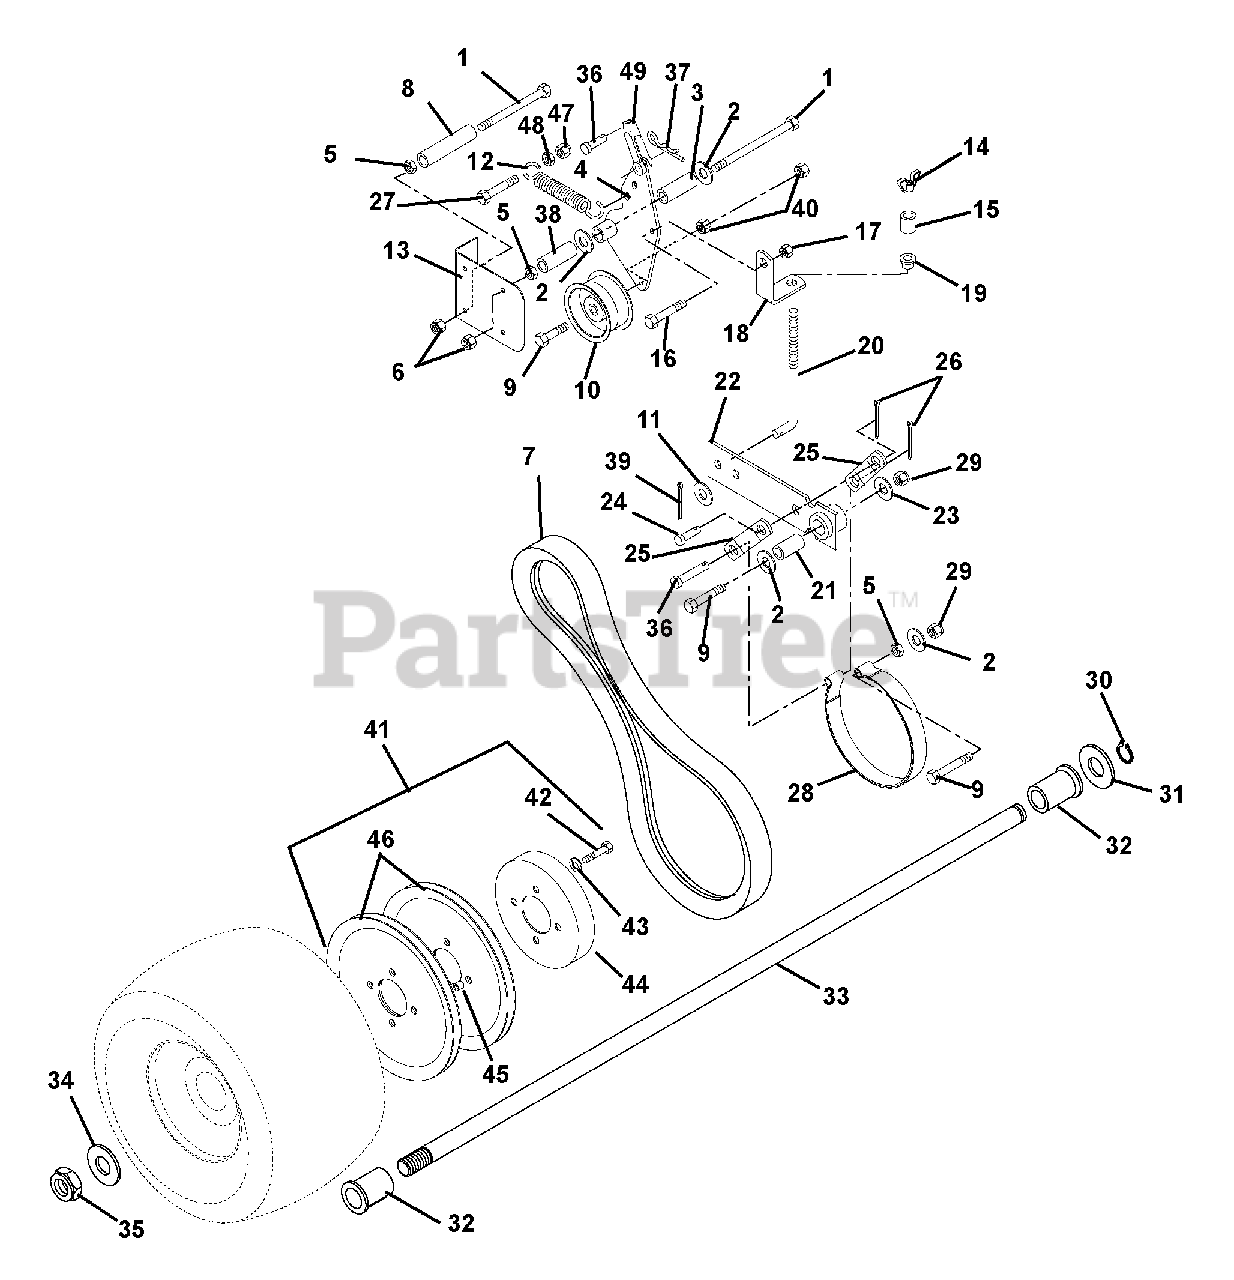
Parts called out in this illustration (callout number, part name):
1	@BLT-HEX .38-16X4.50 GR5 YWZC
2	@WSHR-FL-STL.406X.812X.065 YWZ
3	BUSH.,S.385X.610X1.80 ST
4	WMT - WHEEL CLUTCH ARM
5	@NUT-HEX .38-16 YWZC
6	@NUT-LK-TOP-FLG .38-16 YWZC
7	BELT, TRACTION DRIVE
7	BELT - TRACTION DRIVE - PRO
8	BSHG, SPACER, 3.25X3/8IDX5/8OD
9	@BLT-HEX .38-16X2.00 GR5 YWZC
10	IDLER 2.75X1.25
11	@WSHR-FL-STL.344X.688X.065YWZC
12	SG-TENS .105X1.00X5.0
13	KIT-BELT COVER W/DECALS
14	NUT-NYLK WING .312-18 YWZC
15	BSHG-SLV .391X.688X.52 PM
16	@BLT-HEX .25-20X.75 GR5 YWZC
17	@NUT-LK-NYL .250-20 YWZC
18	BRACKET, BRAKE LINK
19	BSHG-FLG .320X.620X.312 NY
20	ROD, BRAKE
21	BUSH.,S.391X.622X.950 ST
22	WLDMT,BRAKE ARM
23	WSHR-FL-STL .406X1.00X.188 YWZ
24	PIN-CLEV .38X.75 YWZC
25	LINK,BRAKE ARM
26	@PIN-CTR .12X.75 EXTPRSQCT YWZ
27	@BLT-HEX .31-18X2.00 GR5 YWZC
28	ASM, BRAKE BAND, PRO
29	@NUT-LK-NYL .38-16 YWZC
30	RG-RTNG-EXT .906X.078
31	WSHR-FL-STL 1.010X1.505X.062YZ
32	BSHG-FLG 1.010X1.38X1.4X1.65
33	SHAFT, AXLE
34	@WSHR-FL-STL.812X1.50X.135YWZC
35	NUT-LK-JAM-NYL .75-10 YWZC
36	PIN-CLEV .38X1.25 YWZC
37	PIN-HAIR INT .08X.18X1.18 YWZC
38	BUSHING, SPACER .385X.561X1.38
39	@PIN-CTR .09X.75 EXTPRSQCT YWZ
40	@NUT-LK-CTR-JAM .375-16 YWZC
41	ASSY, PULLEY & DRUM
42	@BLT-HEX .31-18X1.50 GR5 YWZC
43	@WSHR-LK .31X.078 REG YWZC
44	DRUM,BRAKE
45	BUSH.,S.385X.625X.475 ST
46	SHEAVE 8"
47	@NUT-LK-CTR .31-18 YWZC
48	@NUT-HEX .31-18 YWZC
49	CLEVIS, .38-24 ADJ.
